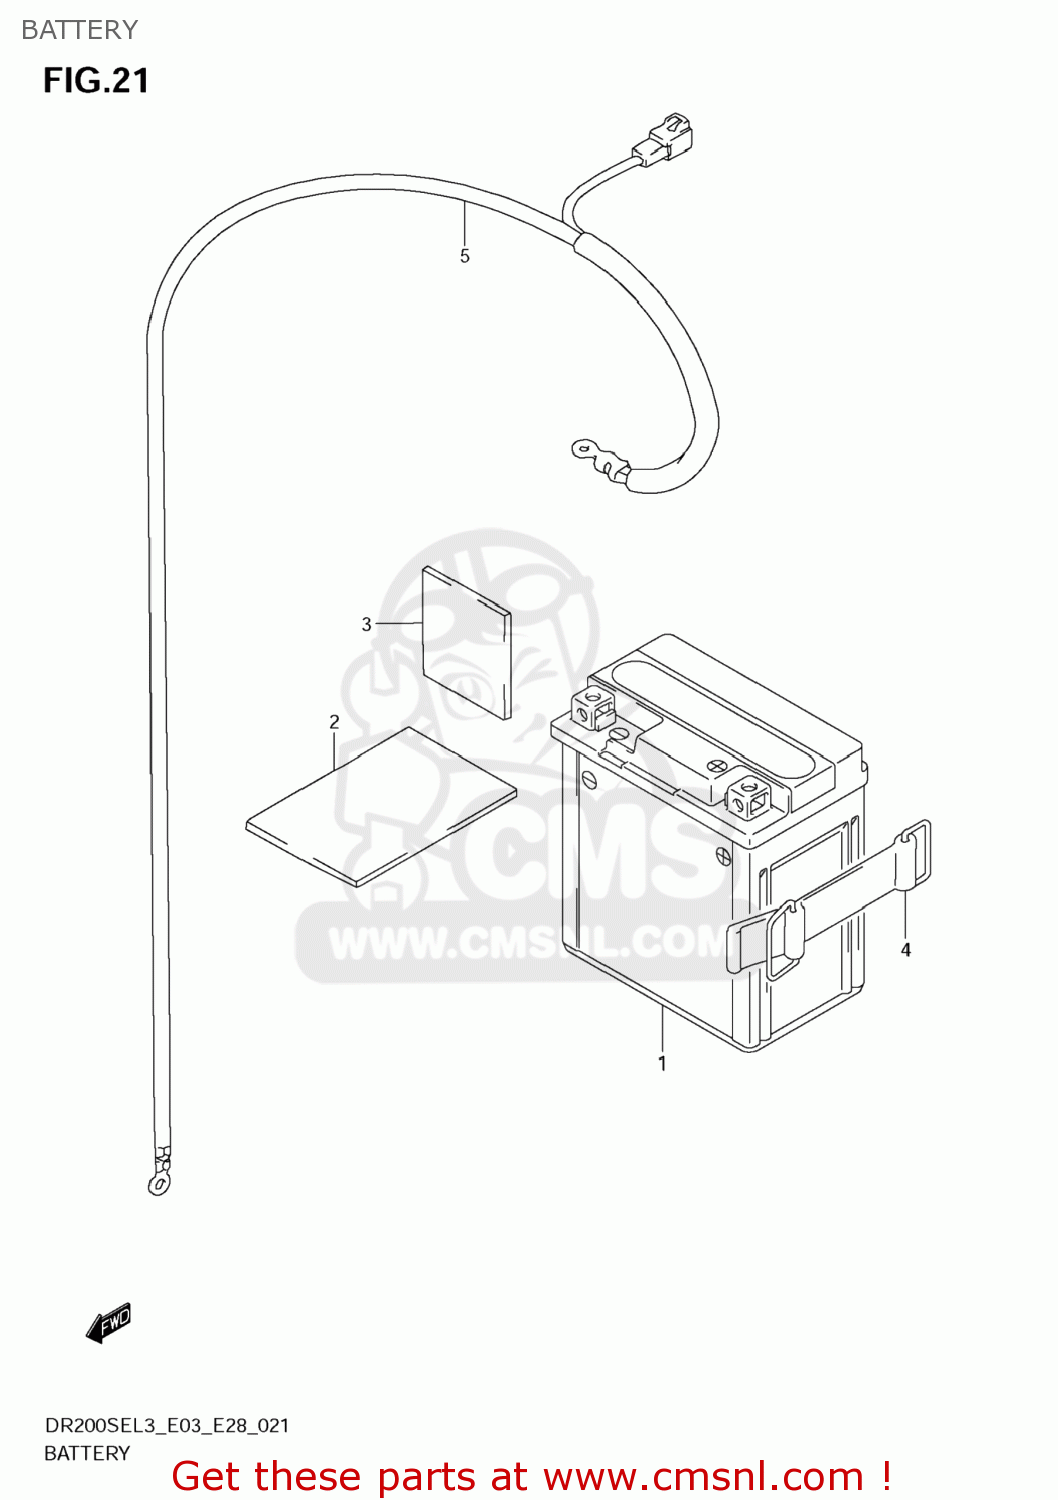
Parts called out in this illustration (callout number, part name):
1	BATTERY ASSY(YTX7L-BS,12V6AH)
2	PROTECTOR
3	CUSHION(30X50X3)
4	BAND
5	WIRE,BATTERY MINUS
